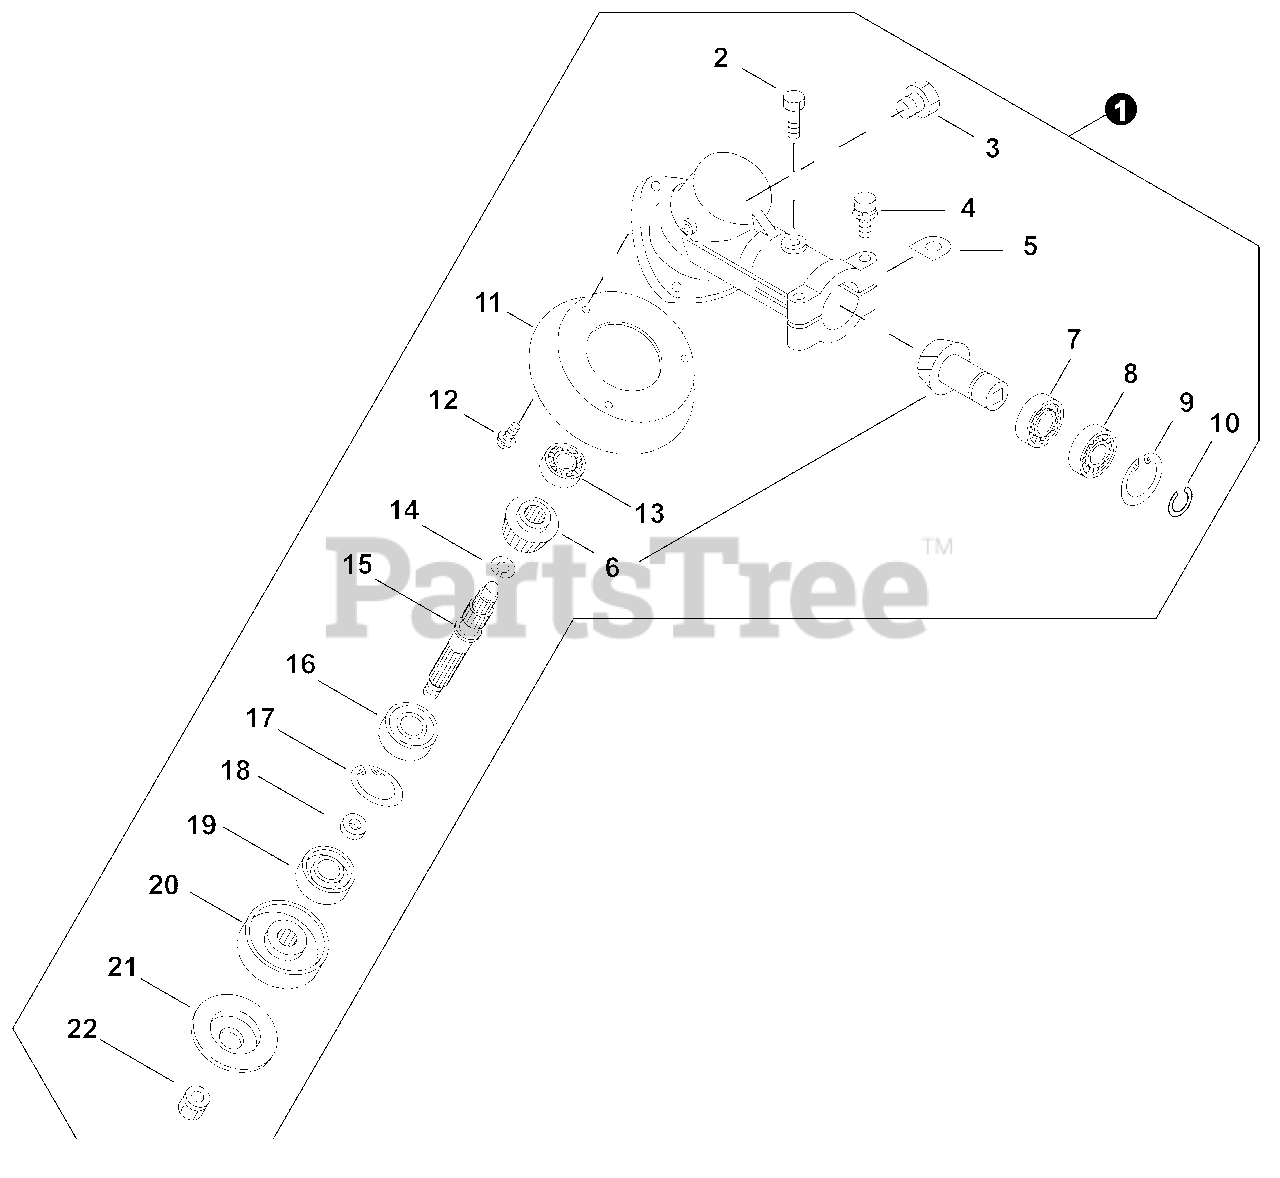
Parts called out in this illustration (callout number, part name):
1	GEAR CASE ASSY
3	BOLT M8×8
4	BOLT M5×30
6	GEAR SET
7	BEARING, BALL 6001
8	BEARING, BALL 6001
9	RING, SNAP 28
10	RING, RETAINING - 12
11	COVER, GEAR CASE
12	SCREW 5×20
13	BEARING, BALL 6000
14	RING, SNAP Ø12
15	SHAFT, GEAR
16	BEARING, BALL 6201
17	RING, SNAP Ø32
18	SPACER 11.8×15×9
19	SEAL, OIL 22
20	PLATE, ADAPTOR - UPPER
21	PLATE, ADAPTOR - LOWER
